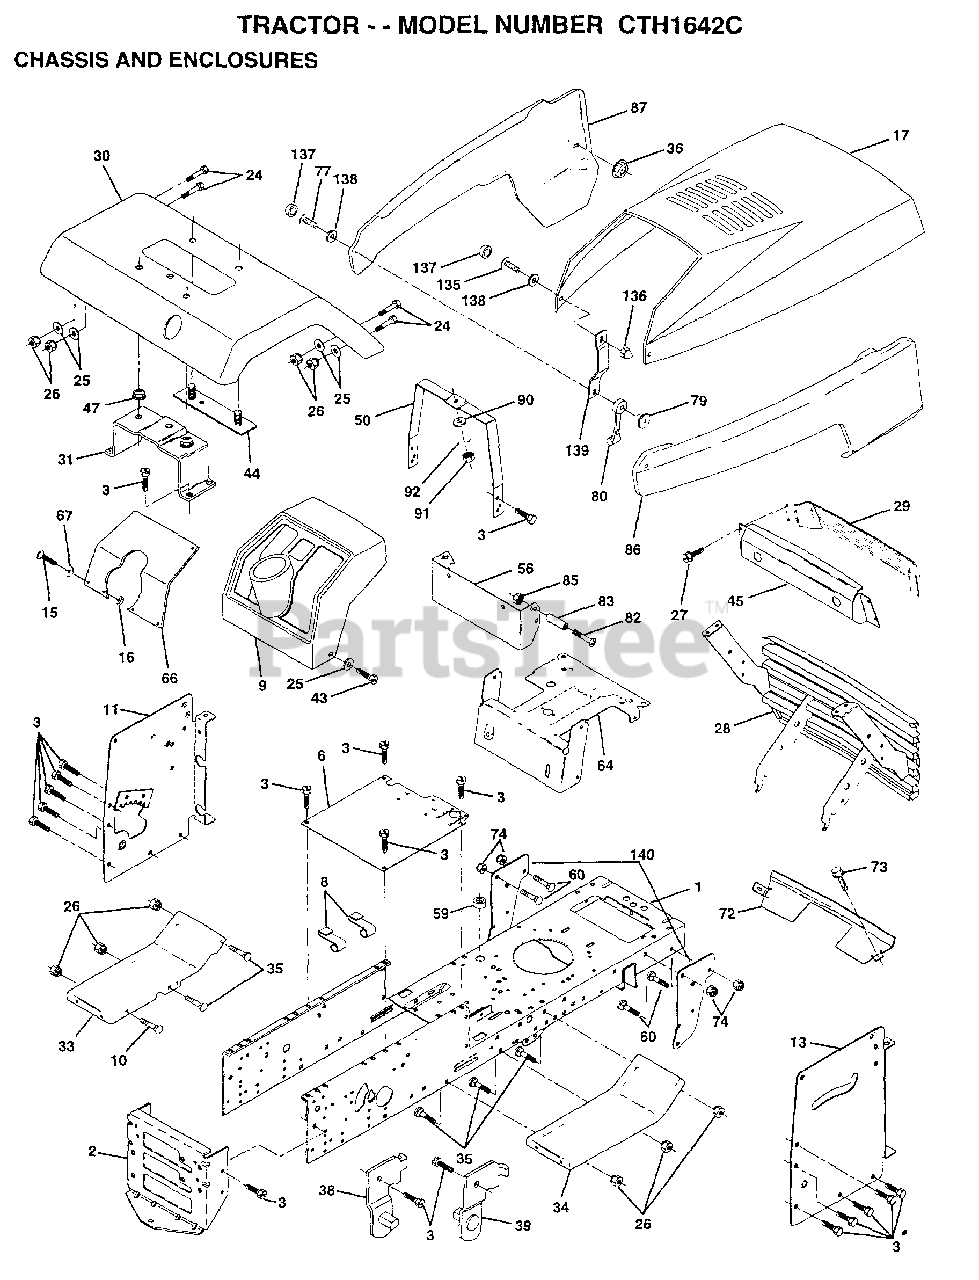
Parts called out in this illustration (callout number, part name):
1	CHASSIS WLDMT 11G
3	SCREW
8	"CLIP,INSULATOR"
9	DASHBOARD BLACK
11	PANEL.DASH.LH.PNT
13	PANEL.DASH.RH.
15	SCREW
17	HOOD PNT YARDPRO
24	BOLT
25	WASHER
26	NUT
28	GRILLE ASM PNT
29	LENS.BAR.CLEAR
30	FENDER PNT
31	BRKT.ASM.FENDER
33	FOOTREST.LH.LT/GT
34	FOOTREST.RH.LT/GT
35	BOLT
36	PAL NUT LT
38	BRACKET ASM LH
39	BRACKET ASM RH
43	SCREW GTV
44	STRAP ASM FENDER
45	BEZEL.ASM.
47	NUT-PUSH YT
50	DASH.SUPT.YP/HUSQ
56	EXT DASH LTYT
60	BOLT
64	DASH.LOWER.LT
66	PLATE.SILKSCREEN
67	WASHER
72	STRAP.PNT.GRILLE
73	SCREW CRT
77	SCREW
79	WELDNUT
80	HOOD LATCH T
82	SCREW
83	SPACER LT
86	PANEL PNT RH SIDE
87	PANEL PNT LH SIDE
90	WASHER PM
92	LOCKWASHER
135	SCREW.10-24X3/8.
136	ACORN NUT RB
137	SNAP CAP LT
138	WASHER LT
139	BKT.SPT.HOOD/PANL
